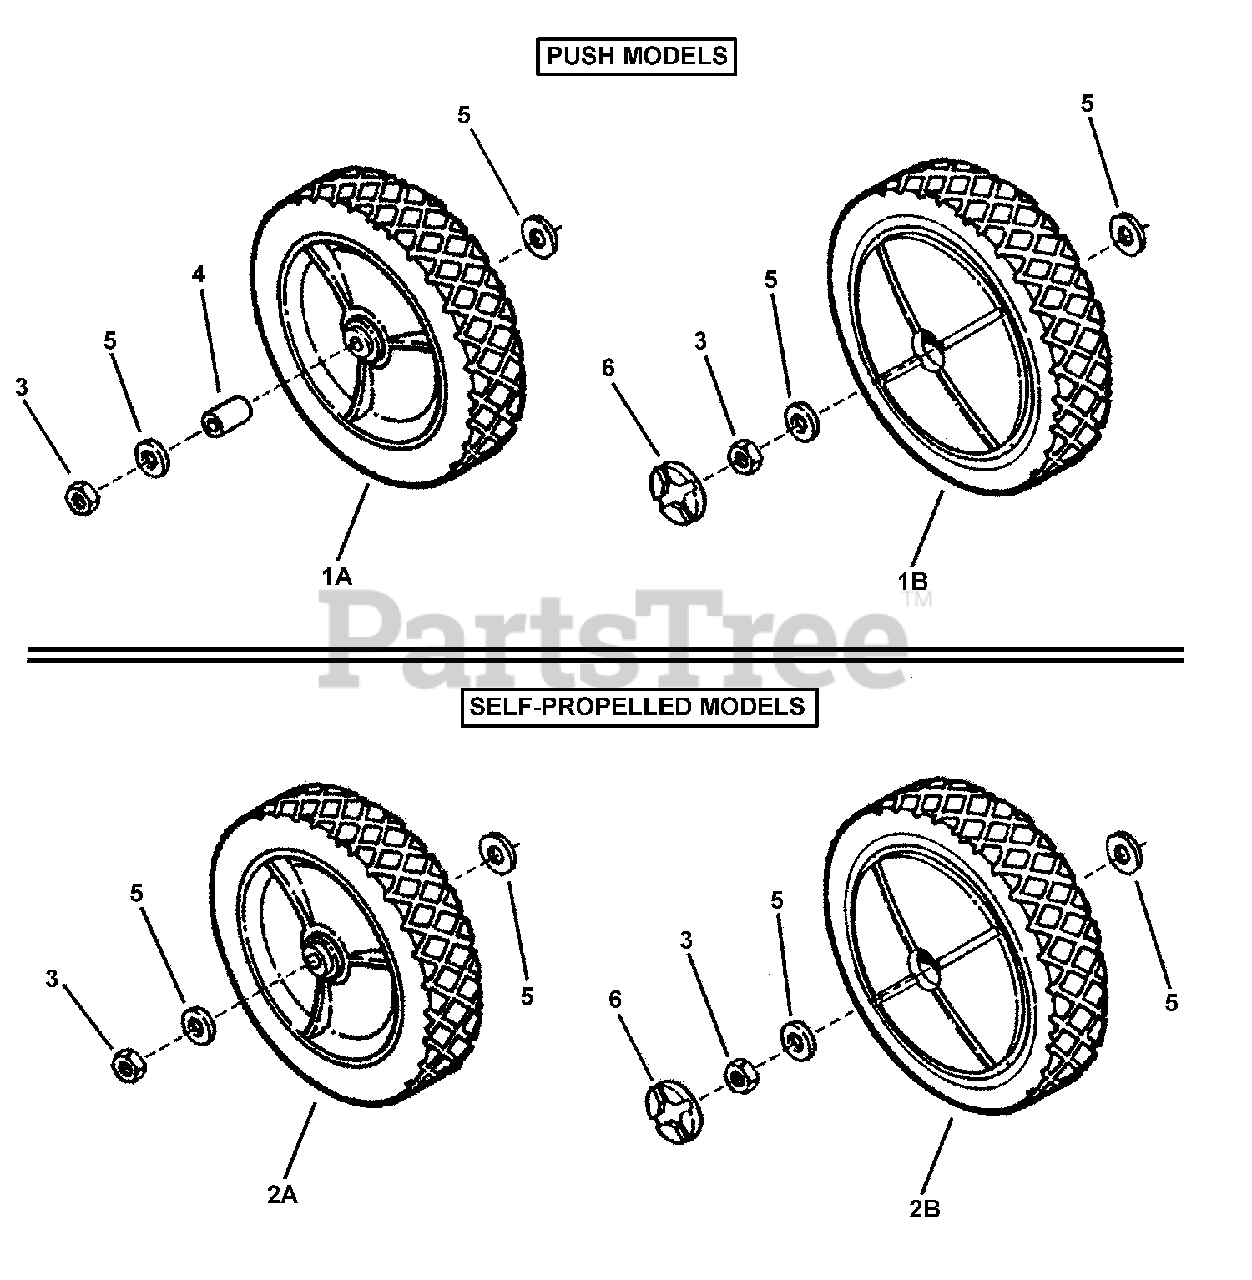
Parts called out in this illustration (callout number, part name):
1A	WHEEL, 10 x 1.75" Plastic (Push Models)
1B	WHEEL, 10 x 1.75" Plastic (Push Models)
2A	WHEEL, 10 x 1.75" Plastic (Self-Propelled Models)
2B	WHEEL, 10 x 1.75" Plastic (Self-Propelled Models)
3	NUT, 7/16-20 Hex Center Lock Jam
4	BUSHING, Axle
5	WASHER, 7/16 x 1" O.D. Flat
6	PLUG, Wheel
